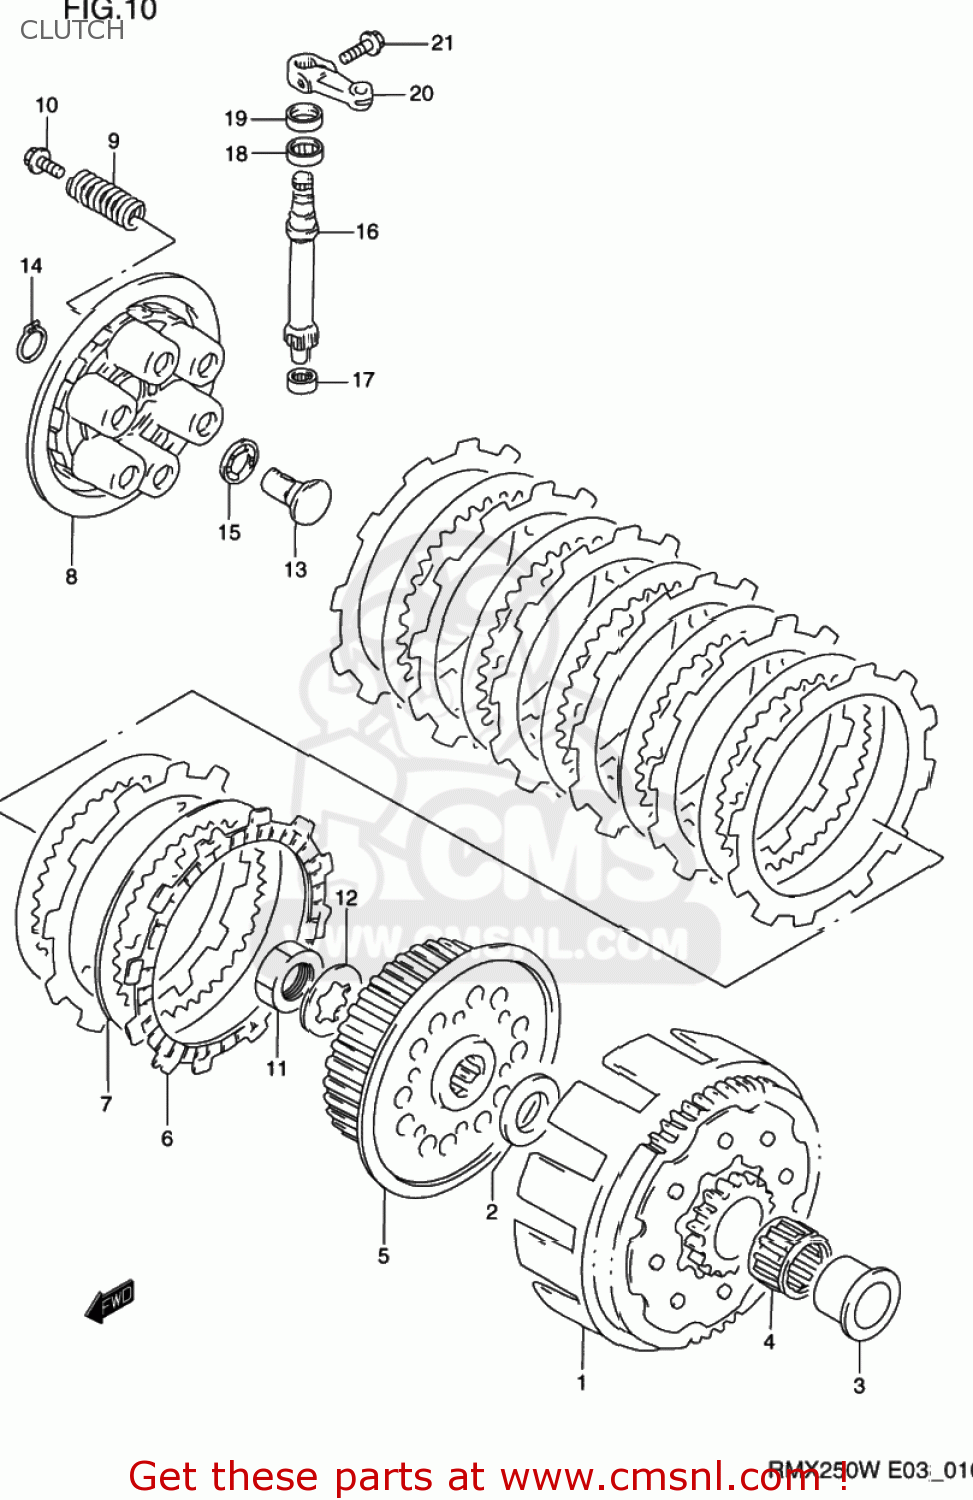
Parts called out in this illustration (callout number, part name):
1	GEAR ASSY,PRI DRIVEN
2	WASHER(22X38X2)
3	SPACER,PRIMARY DRIVEN GEAR
4	BEARING(29X34X21.8)
5	HUB,CLUTCH SLEEVE
6	PLATE,CLUTCH DRIVE (NAS)
7	PLATE,CLUTCH DRIVEN(T:1.6) (NAS)
8	DISC,CLUTCH PRESSURE
9	SPRING
10	BOLT(5X25)
11	NUT
12	WASHER,LOCK
13	RACK,CLUTCH RELEASE
14	CIRCLIP,10MM
15	BEARING(10X22X2.8)
16	PINION,CLUTCH RELEASE(NT:12)
17	BEARING(9X13X10)
18	BEARING(12X16X10)
19	SEAL,OIL(10X17X5)
20	ARM,CLUTCH RELEASE
21	BOLT
